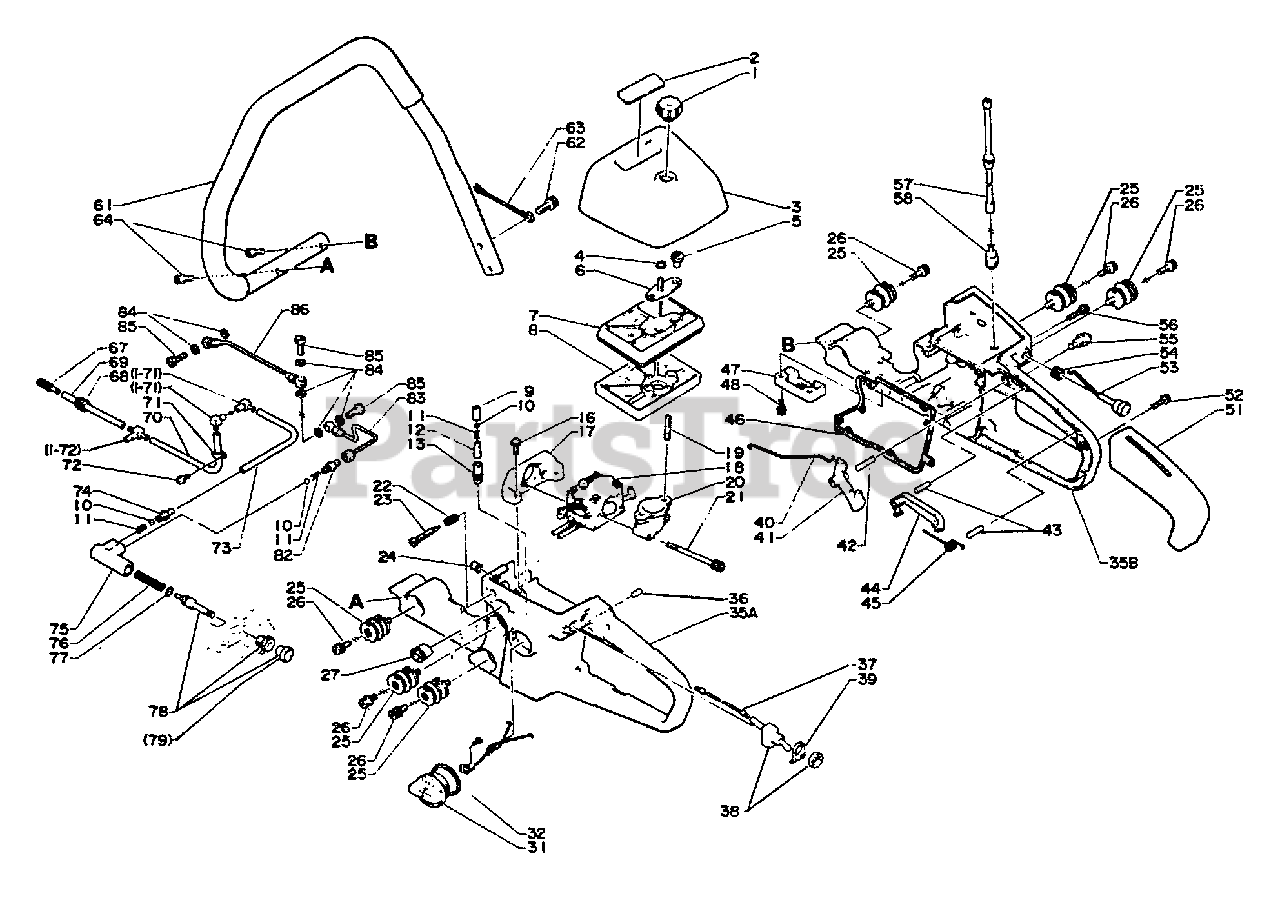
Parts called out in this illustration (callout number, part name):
2	MODEL PLATE
3	COVER, AIR FILTER
9	BREATHER
10	VALVE, BALL
11	SPRING, VALVE
12	BREATHER
13	CONNECTOR
16	SCREW 5×14
17	CASE, CARBURETOR
18	CARBURETOR
19	STUD
20	PIPE, INTAKE
21	BOLT 5×75
22	SPRING, THROTTLE
24	GROMMET
25	CUSHION
26	SCREW - 5×15
27	GROMMET
32	O-RING 29
35	REAR HANDLE ASSY
35A	REAR HANDLE ASSY
35B	REAR HANDLE ASSY
36	PIN, LOCATING 5×10
37	LEAD - GROUND
38	SWITCH ASSY, STOP
39	LABEL, ON-OFF
40	ROD, THROTTLE
41	TRIGGER, THROTTLE
42	PIN, SPRING 5×25
43	PIN, SPRING 4×20
44	LOCKOUT, THROTTLE
45	SPRING, LOCKOUT RETURN
46	GASKET, FUEL TANK
47	COVER, PUMP
48	SCREW 4×12
51	GRIP, REAR HANDLE
52	BOLT 4×16
53	ROD, CHOKE
54	GROMMET, RUBBER
55	LATCH, THROTTLE
56	BOLT 4×20
57	PIPE, FUEL
58	FILTER, FUEL
61	HANDLE, FRONT
62	BOLT 6×20
63	LEAD - GROUND
64	BOLT 5×20
67	FILTER, OIL
69	PIPE - 3×6×220
70	PIPE, OIL
71	CLIP
72	SCREW 4×10
73	PIPE, OIL
74	CONNECTOR
75	BODY, OIL PUMP
76	SPRING, OIL PUMP
77	O-RING 6 MM
78	PUMP PISTON
79	PUSH BUTTON
82	CONNECTOR
83	PIPE, OIL
85	HOLDING BOLT
86	PIPE, OIL
